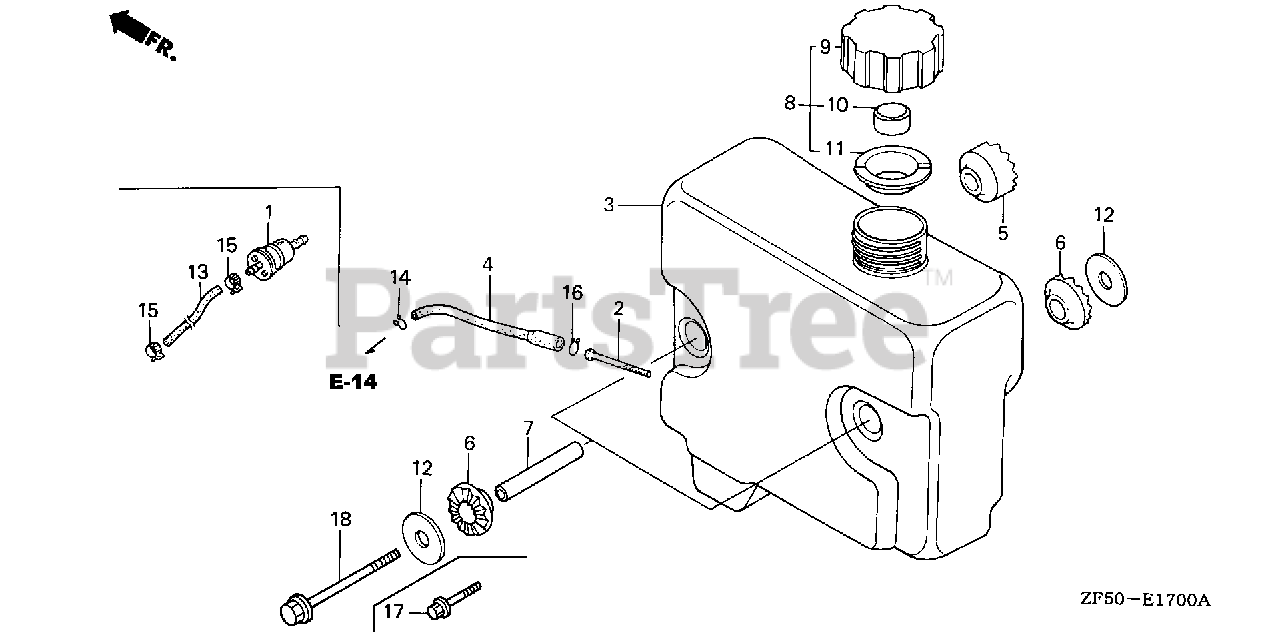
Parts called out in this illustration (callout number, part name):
1	STRAINER, FUEL
13	BULK HOSE, FUEL (4.5X3000)
15	CLAMP, TUBE (D8.5)
17	BOLT, FLANGE (8X16)
